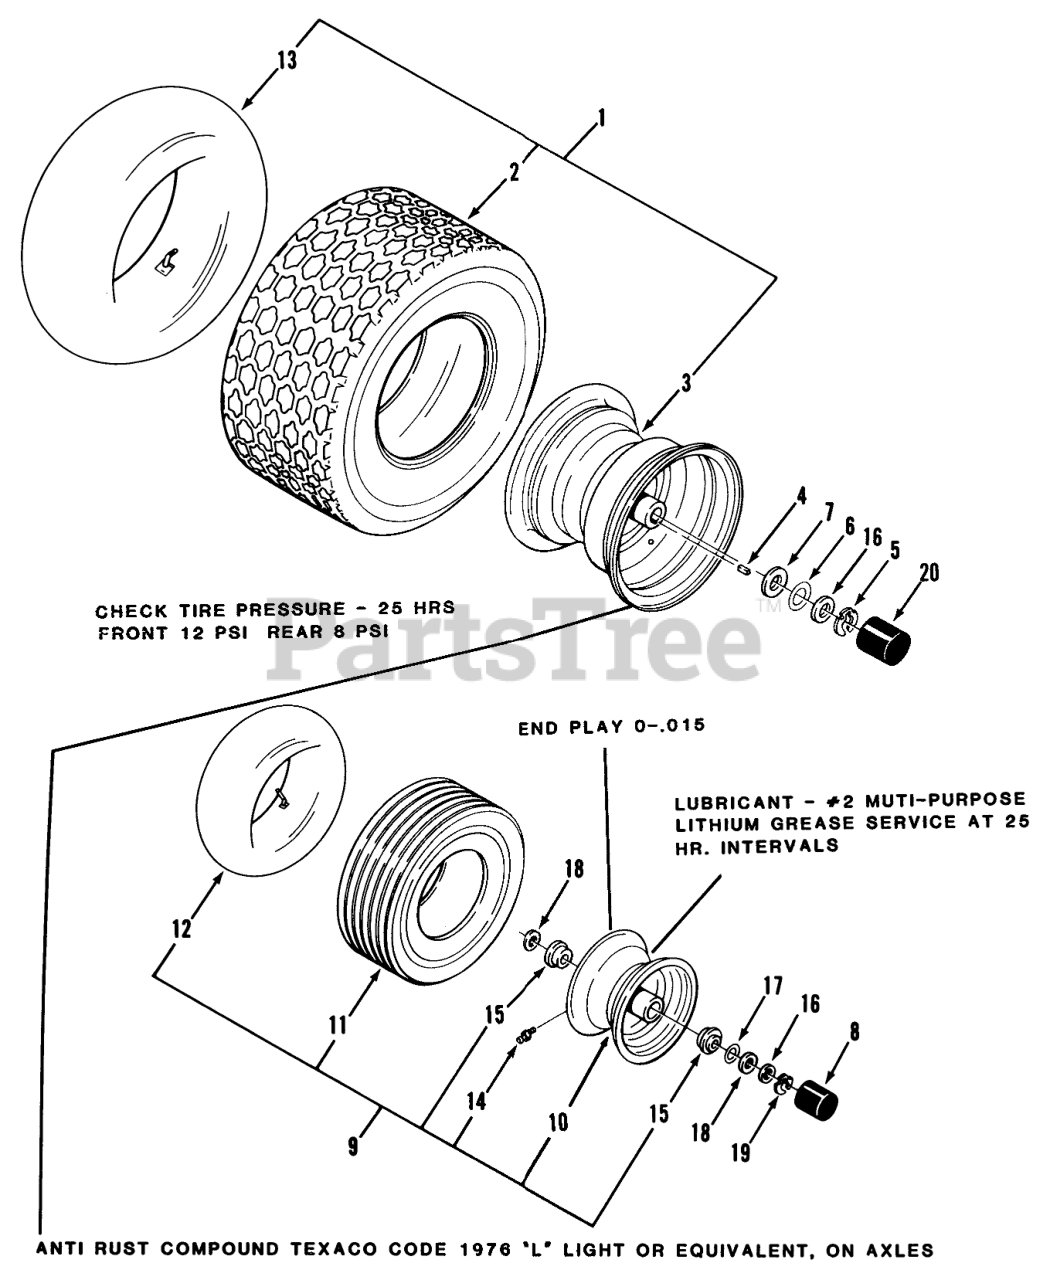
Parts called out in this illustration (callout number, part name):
1	Rear Wheel Assembly 18 x 9.50 x 8
2	TIRE-18X9.50-8 TT RS
3	WHEEL ASS'Y 8"X7
4	Key
5	Retainer
6	Washer
8	HUB CAP-FLAT BLACK
9	Front Wheel Assembly 11 x 4.00-5
10	WHEEL ASS'Y
11	TIRE 11 X 400-5 RIB
12	TUBE-TIRE 11X4.00-5
13	TUBE-TIRE
14	ZERK-GREASE
15	BEARING-WHEEL
16	WASHER-FLAT
17	WASHER-SHIM
18	WASHER
19	KLIP-RING .75"
20	HUBCAP
